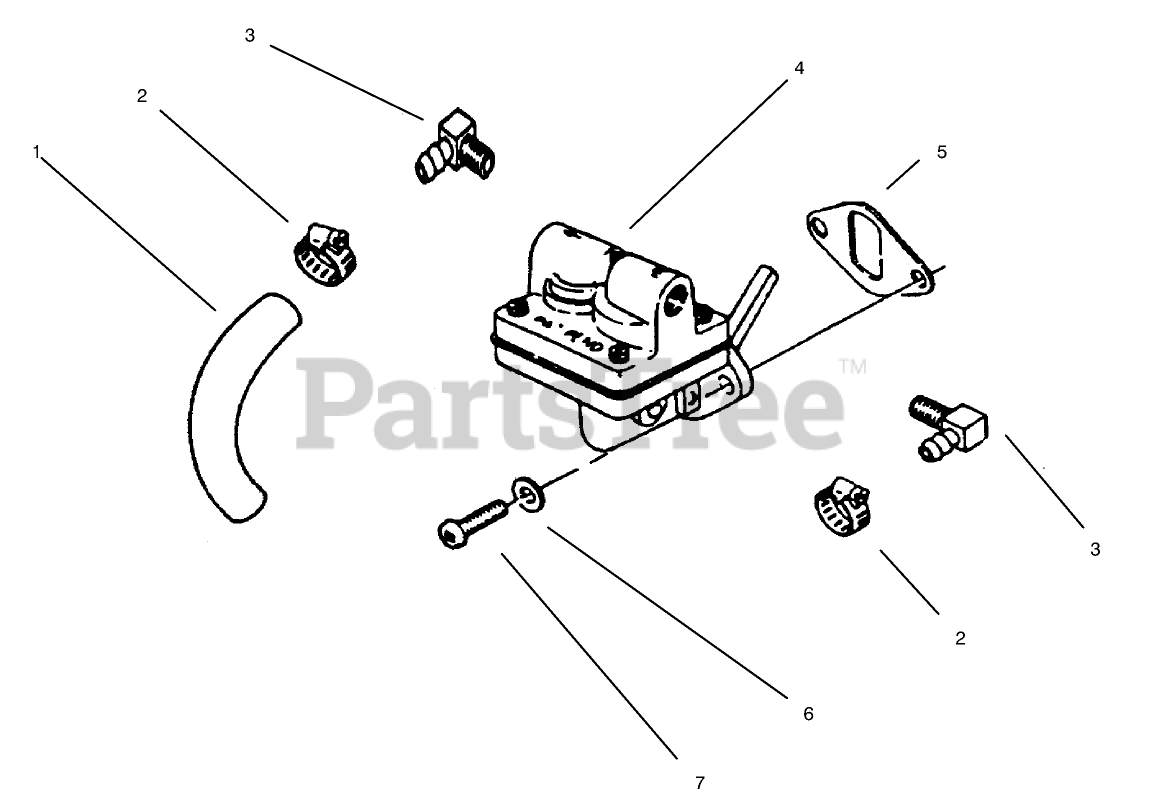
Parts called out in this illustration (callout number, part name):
1	Line-Fuel
2	Clamp
3	Connector-90?
4	Pump ASM-Fuel INC 57
6	Washer
7	Screw-F.H.
